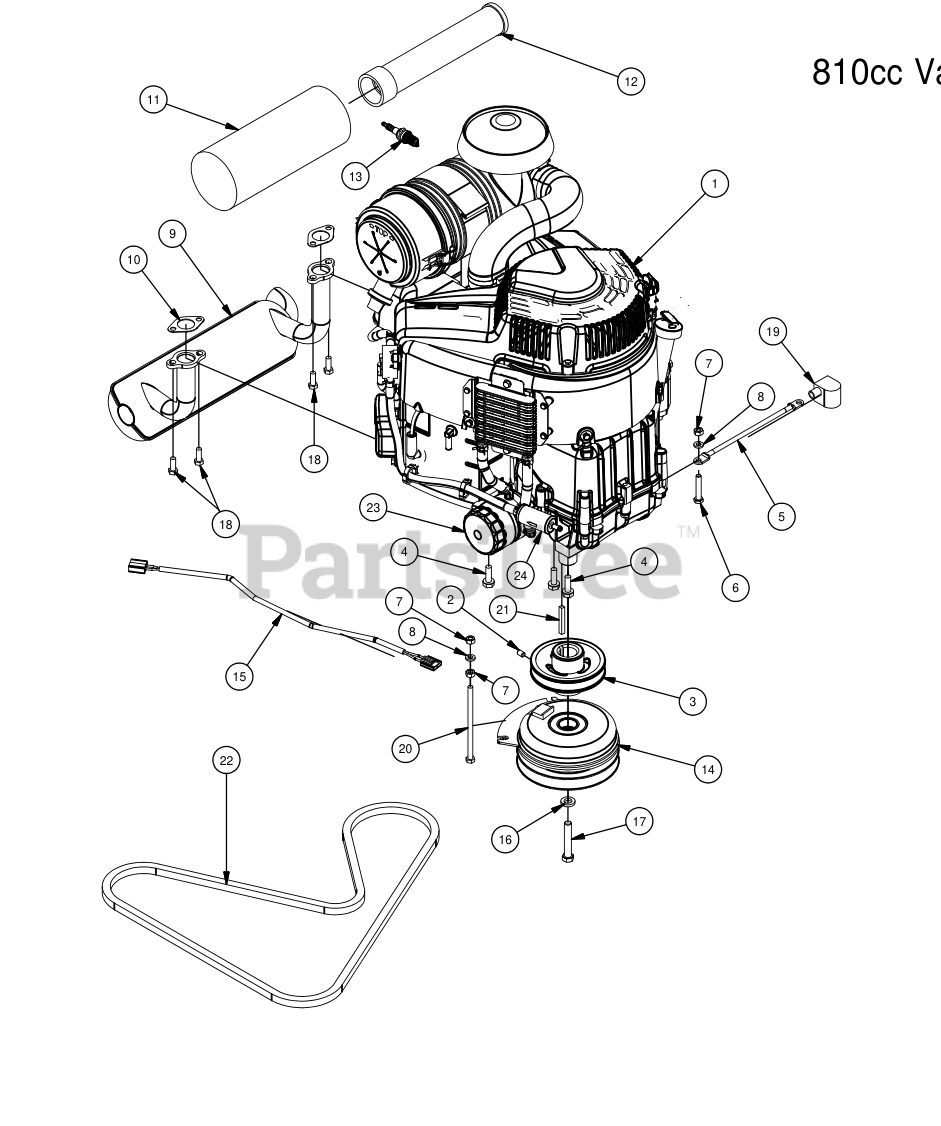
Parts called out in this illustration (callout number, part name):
1	810 Vanguard
2	3/8" Set Screw
3	4 3/4 Motor Pulley
4	3/8 x 1 1/8 bolt
5	Ground Cable
6	5/16" x 1 3/4" Hex Bolt
8	5/16" Lock Washer
9	Briggs Exhaust
10	Exhaust Gasket
11	Canister Air Filter- Outer
12	Canister Air Filter- Inner
13	Spark Plug
14	Clutch Assembly
15	Clutch Pigtail
16	7/16" Lock Washer
17	7/16" x 2 1/2" Hex Bolt
18	Torx Bolt-Exhaust
19	Black Boot For Ground Cable
20	5/16-18 x 5-1/2 GR 5 Hex Bolt
21	1/4 x 2 Square key Stock
23	Briggs Oil Filter
24	Universal Fuel Filter
